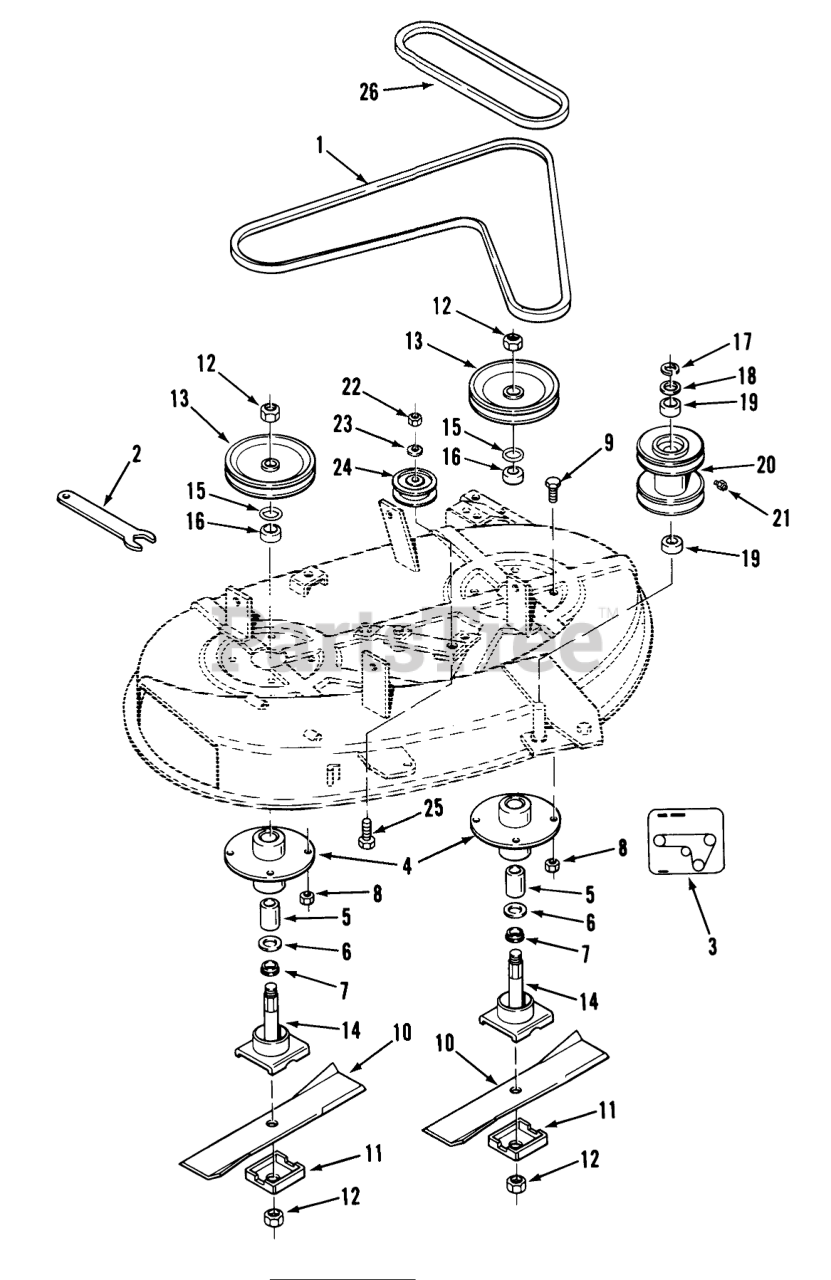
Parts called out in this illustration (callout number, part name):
1	V-BELT
2	Spindle Wrench
3	Decal-Routing
4	Spindle
5	BEARING SPACER
6	RING-RETAINING
7	SPACER-SPINDLE
8	Nut
9	Bolt
10	Blade
11	Cup
12	NUT-LOCK NI
13	DECK PULLEY
14	SPINDLE SHAFT WA
15	Washer
16	BEARING-BALL
17	RETAINING RING
18	O RING
19	BEARING-BALL
20	PULLEY-COUNTER SHAFT
21	Zerk
22	NUT
23	Washer
24	Pulley
25	Bolt
26	V-BELT
